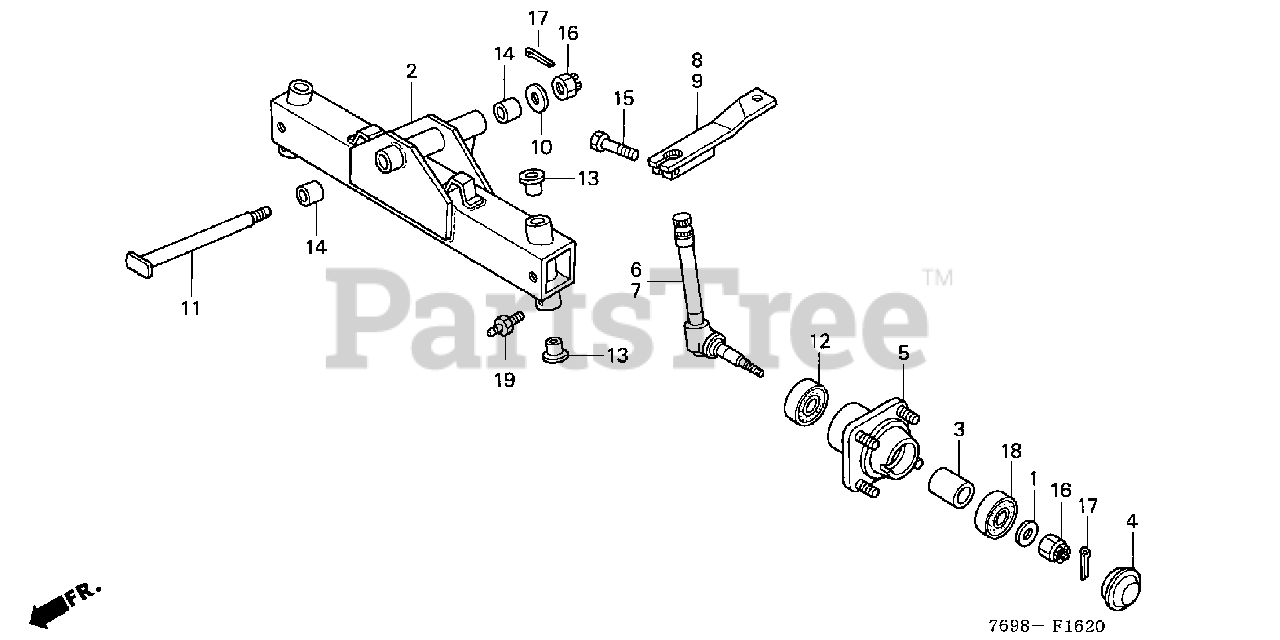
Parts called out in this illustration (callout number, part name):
1	WASHER (14MM)
3	COLLAR, FR. AXLE
4	CAP, FR. HUB
5	HUB, FR. AXLE
6	KNUCKLE, R. FR.
7	KNUCKLE, L. FR.
8	ARM, R. FR. KNUCKLE
9	ARM, L. FR. KNUCKLE
10	WASHER, THRUST (14X30X2.5)
11	PIN, CENTER
12	BEARING, RADIAL BALL (62/22)
13	BUSH (28X25X20)
14	BUSH (20X18X20)
15	BOLT, HEX. (12X40)
16	NUT, CASTLE (14MM)
17	PIN, COTTER (3.0X45)
18	BEARING, RADIAL BALL (6205UU)
19	FITTING, GREASE (A.76)
